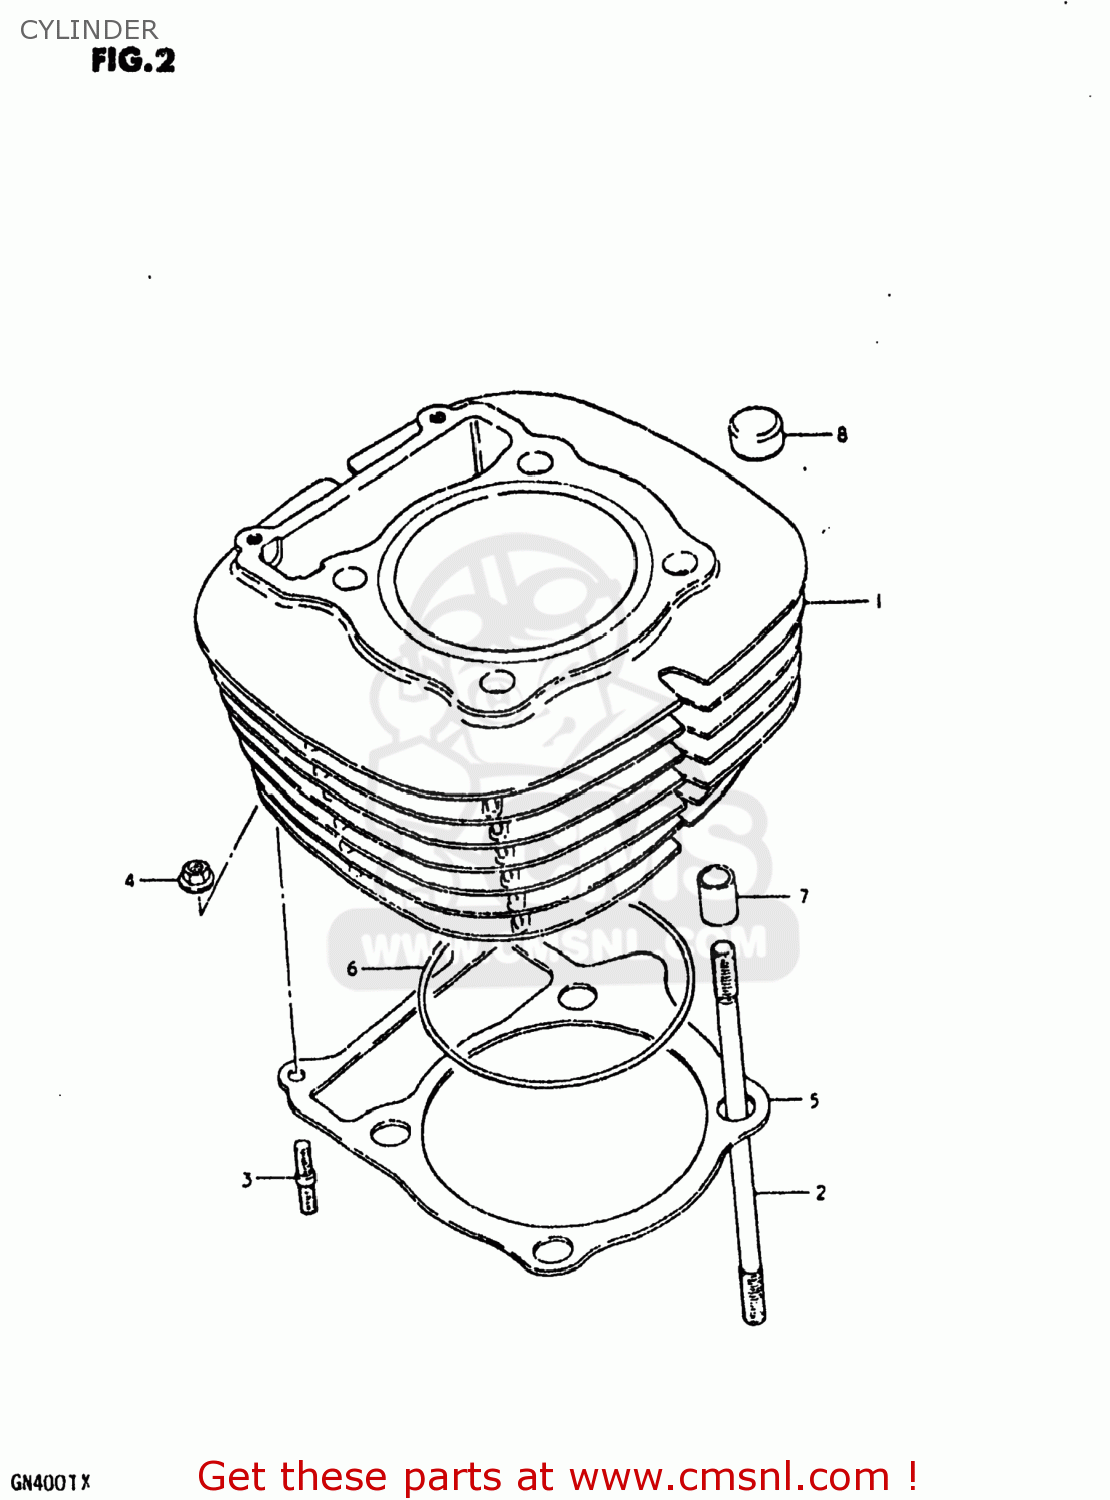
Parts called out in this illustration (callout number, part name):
1	CYLINDER
2	STUD
3	STUD 6X20
4	NUT
5	GASKET,CYLINDER (MCA)
6	O RING(D:2,ID:87)
7	PIN
8	PAD,CYLINDER HEAD
